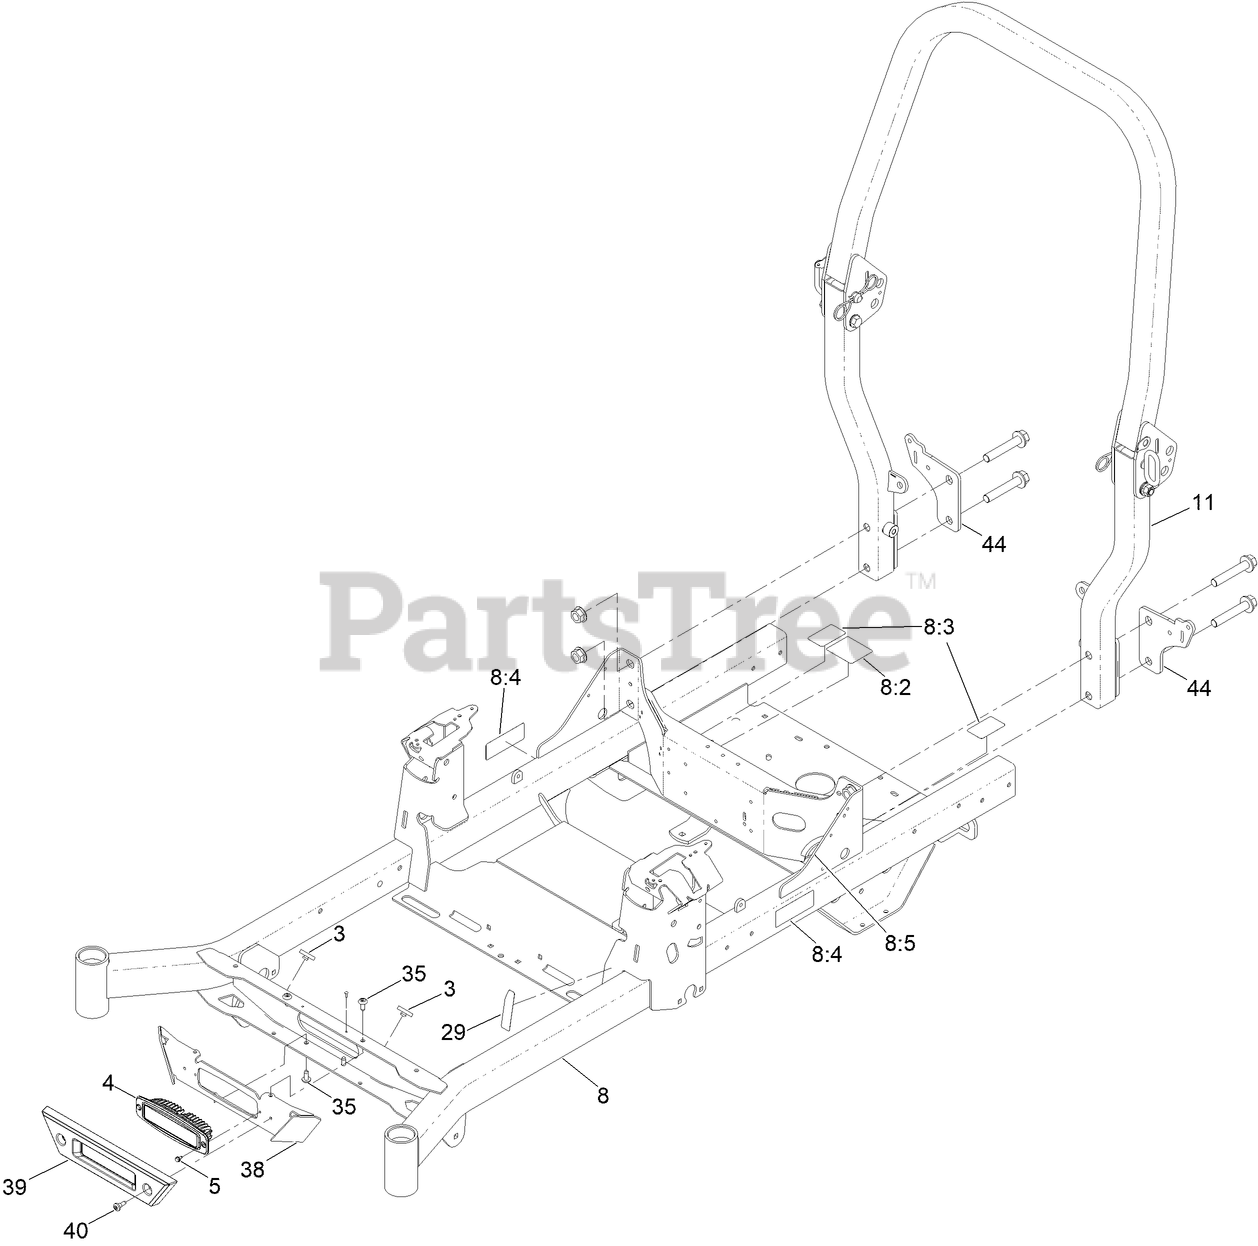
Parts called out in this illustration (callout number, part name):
3	BUMPER-PUSH-IN, RUBBER
4	MOUNT-FLUSH, LIGHT
5	SCREW-HWH
8	FRAME-48/52, MR
8:2	DECAL-ROUTING, BELT
8:3	DECAL-RELEASE, DRIVE
8:4	DECAL-WARNING
8:5	STRIP-SEAL
11	ASM-ROPS, MR
29	DECAL-FILL, FUEL
38	BRACKET-LIGHT [RED]
39	BUMPER-FRONT
40	SCREW-SHOULDER
